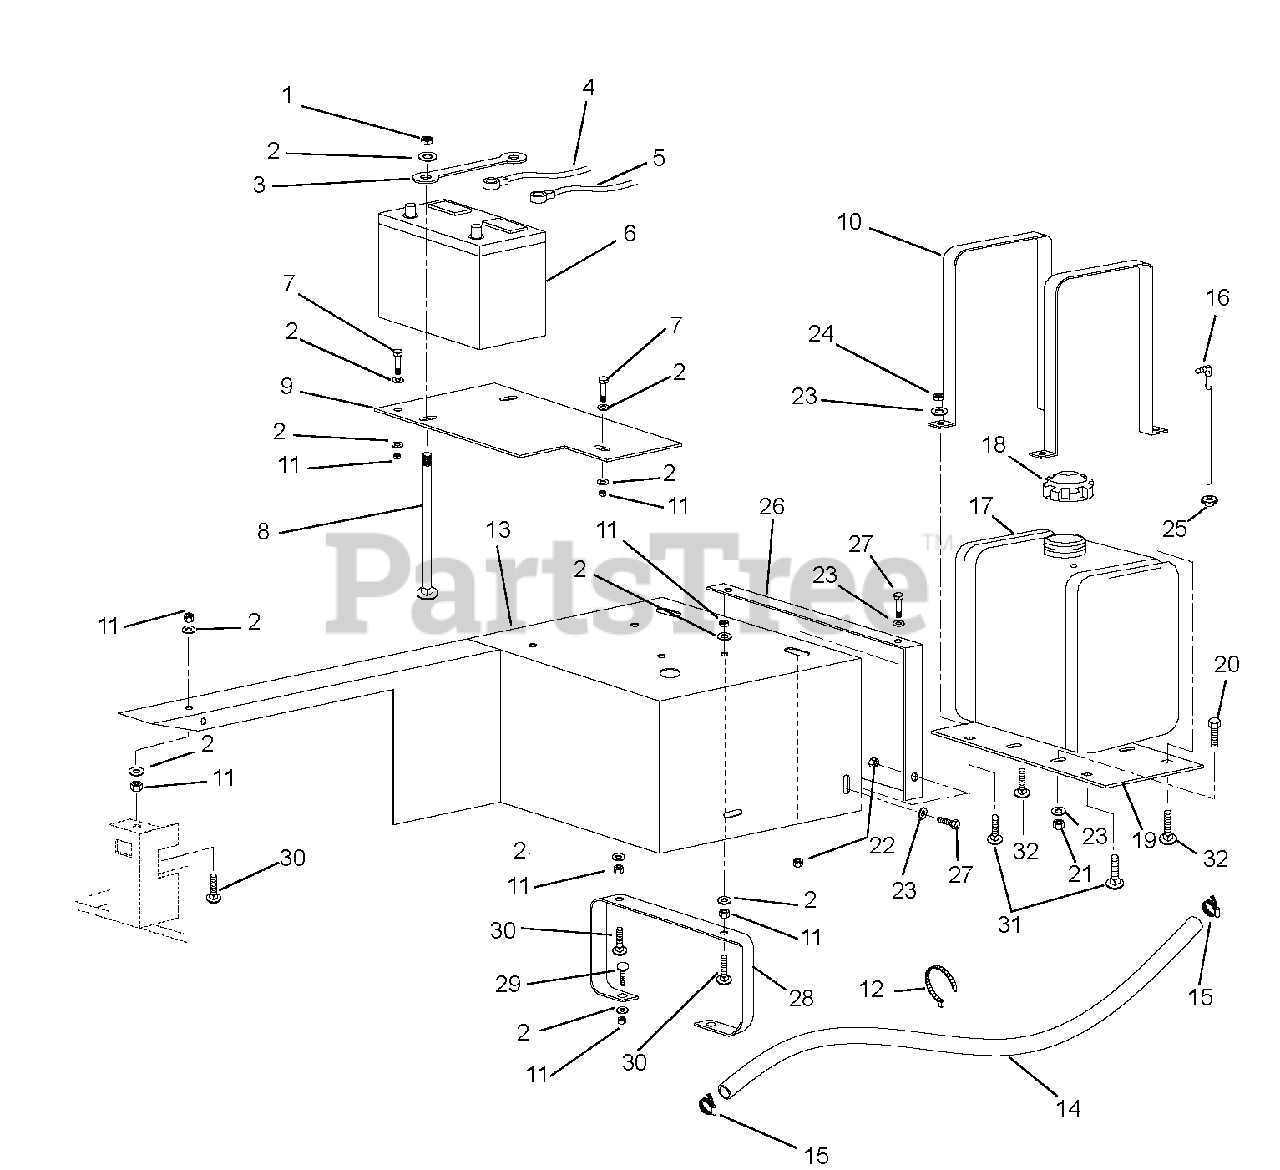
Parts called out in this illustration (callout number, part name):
1	Nut, Hex Jam Nylock .38-16
2	Washer, Flat .38
3	Plate, Battery Hold Down
4	Cable, Battery Positive
5	Cable, Battery Ground
7	Cap Screw, Hex Head .38-16 x 1.00
8	Bolt, Carriage .38-16 x 8
9	Plate, Battery Mounting
10	Strap, Fuel Tank Mounting
11	Nut, Lock .38-16 Crimp
12	Cable Tie .187 x 14.25
13	Weldment, Belt Guard
14	Hose, Fuel .25 I.D.
15	Clamp, Hose Worm Drive Stainless Steel
16	Assembly, Fuel Pickup
17	Tank, Six Gallon Fuel
18	Cap, Vented Fuel Black
19	Mounting Plate, Fuel Tank
20	Cap Screw, Hex Head .312-18 x 1.00
21	Nut, Hex Serrated Flange .312-18
22	Nut, Locking Center .31-10
23	Washer, Flat .312
24	Nut, Hex Nyloc .312-18
25	Fitting, Bulkhead
26	End Plate, Belt Guard
27	Cap Screw, Hex Head .312-18 x .75
28	Stand, Belt Guard
29	Bolt, Carriage .38-16 x 1.00
30	Bolt, Carriage .38-16 x 1.25
31	Bolt, Carriage .312-18 x 1
32	Bolt, Carriage .312-18 x 1.75
